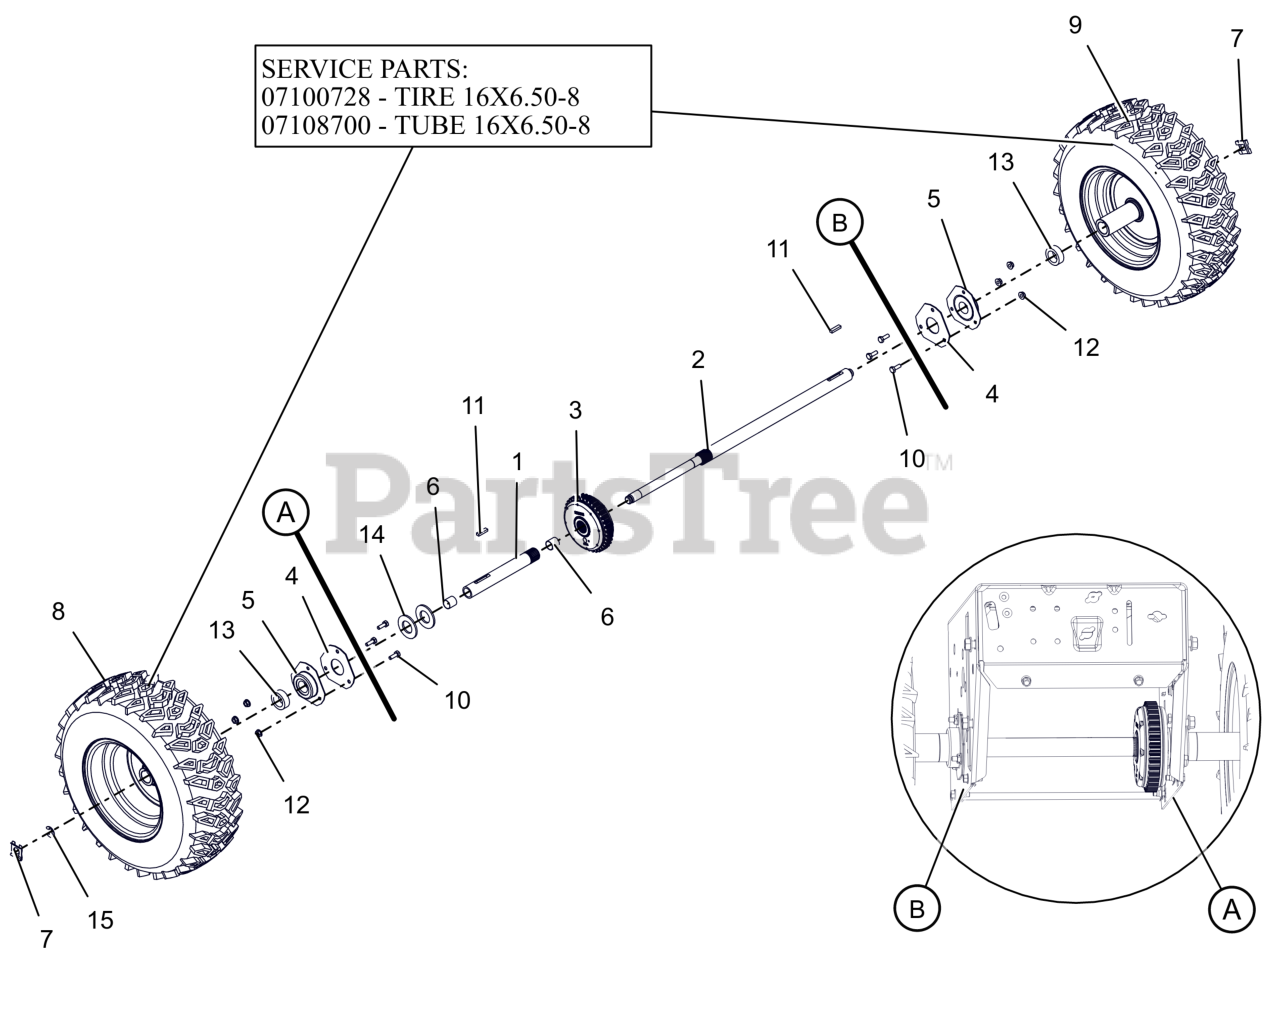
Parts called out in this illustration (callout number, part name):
1	AXLE, SHORT-AUTO W/BUSHINGS
2	AXLE, LONG-PRO AUTO DIFF
3	DIFFERENTIAL, AUTOMATIC
4	PLATE, BEARING SPACER
5	BRG-FLG 1.003/1.000 3 BOLT
6	BSHG-SLV .706X.764X.75 BRZ
7	CLIP, SNAP .625 DIA
8	TIRE/WHEEL,RH 16X6.5-8 DIFF T2
8	TIRE, 16X6.50-8 K478
8	TUBE
9	TIRE/WHEEL,LH 16X6.5-8 DIFF T2
9	TIRE, 16X6.50-8 K478
9	TUBE
10	BLT, HEX .25-20X.75 G5 ZCC
11	KEY-RECT .25X.188X1.00
12	NUT-LK-CTR-FLG .25-20 ZC120
13	SPACER, PRO AXLE BEARING
14	WSHR, FLT 1.062X2.000X.134 ZCC
15	RG-RTNG-EXT .625X.042
